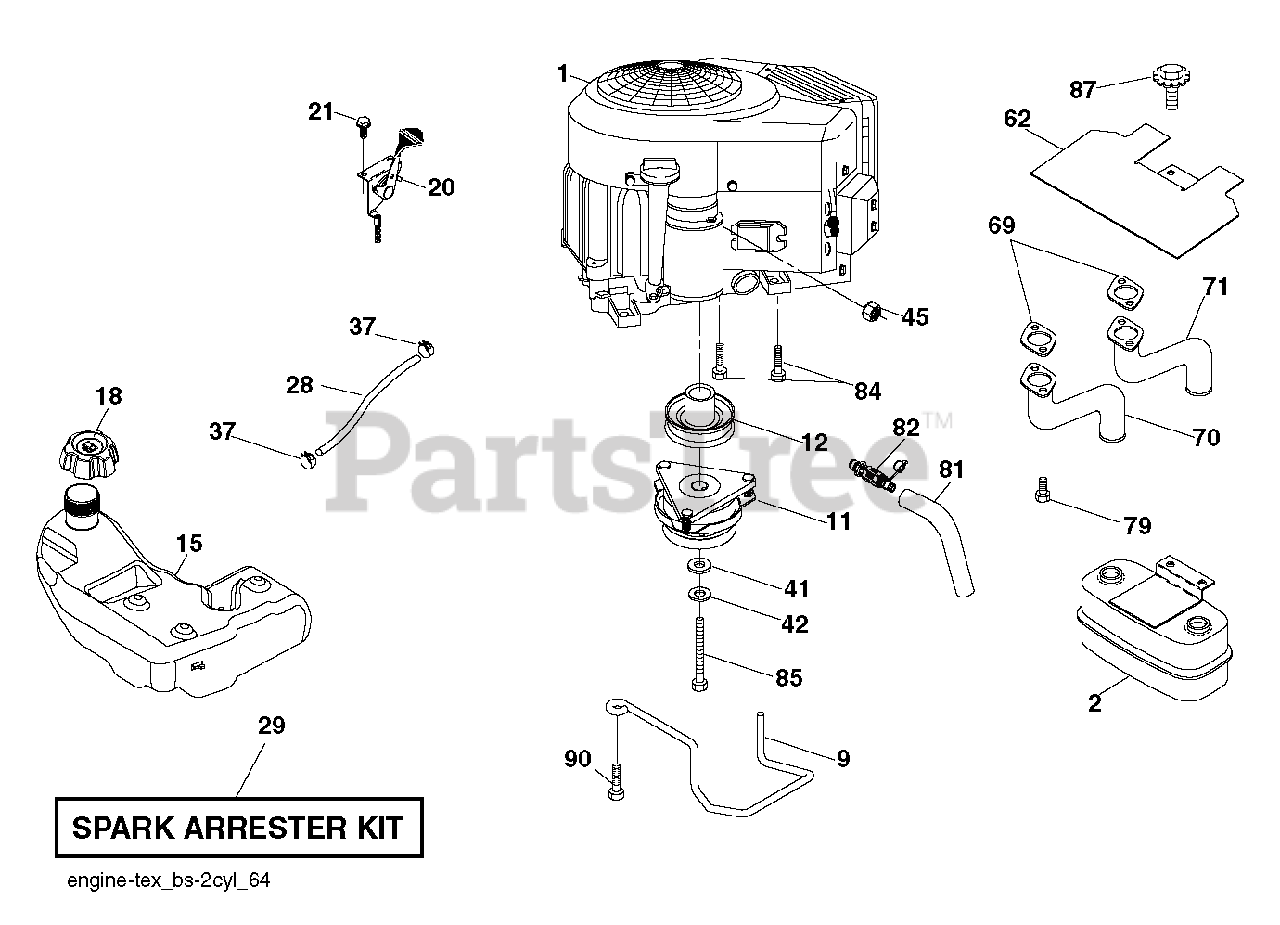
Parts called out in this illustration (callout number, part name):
2	MUFFLER.TWIN.CYL.LOW.TONE
9	KEEPER.BELT.ENGINE.4.2
11	CLUTCH.ELECTRIC.LT.48"*
12	PULLEY.ENGINE.TUFFTORQ
15	TANK.ASSY.3.GAL.EPA
18	CAP.ASM.FL.RITCH.3"E10.SYM.498
20	CONTROL.TH/CK.COBRA.B&S.TWN.
21	SCREW.#10 X 0.750.BOS
28	LINE.FUEL.64"REAR.EMIS
29	KIT.SPARK ARRESTOR 794945 B&S
37	HOSE CLAMP
42	LOCKWASHER
45	NUT
62	RP SHIELD HEAT MUFFLER
69	GASKET.MUFFLER
70	RP.EXHAUST.TUBE.LH.BS/TWIN
71	EXHAUST.TUBE.RH.BS/TWIN
79	SCREW.SOCKET.HEAD.5/16-18
81	TUBE, DRAIN OIL ASM.
82	VALUE.OIL.DRAIN
84	SCREW.3/8-16
85	BOLT HEX 7/16-20X4-1/4"
87	BOLT, 5/16-18 X 1 3/4
90	SCREW 3/8-16X1
